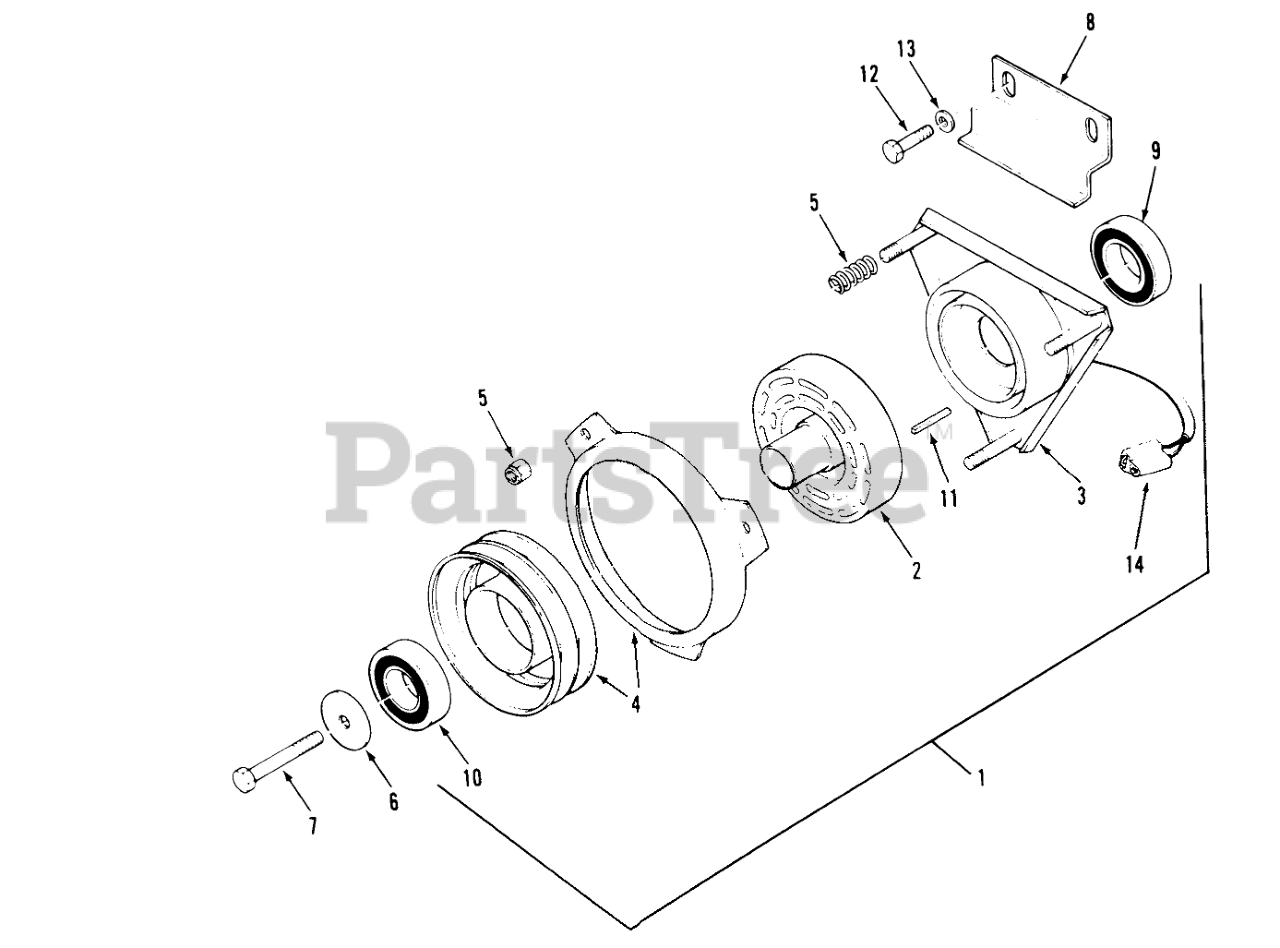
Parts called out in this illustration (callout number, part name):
1	Electric Clutch-Complete (Incl. Ref.s #2, 3, 4, 5, 9, 10, & 14)
2	Rotor & Armature Asm (Incl. Ref. #4 &10)
3	Field (Incl. Ref. #9)
5	ACCESS SPRING & NUT
6	RETAINER-BEARING
7	SCREW-HH
8	BRACKET-CLUTCH B
9	BEARING-FIELD ASS'Y
10	BEARING-ELEC CLUTCH
11	KEY-SQUARE
12	SCREW-HH
13	WASHER-FLAT
14	CONNECTOR BODY B
